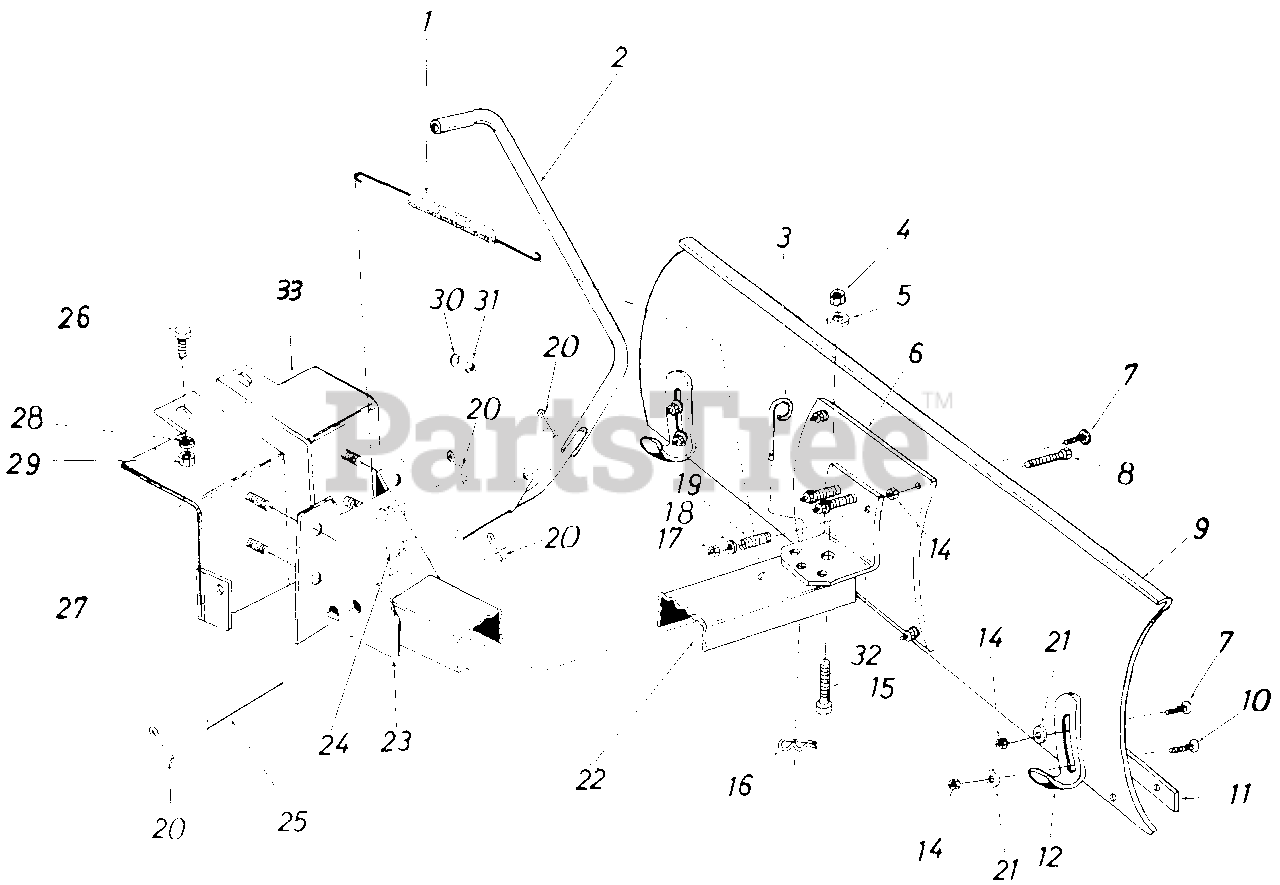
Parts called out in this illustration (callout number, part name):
1	Extension Spring
2	Lift Handle Ass'y.
3	Pivot Lock Pin
4	Hex Cent. L-Nut 1/2-13 Thd.
5	Fl-Wash. 17/32" I.D. x 1.25" Lg.
6	Reinforcement Plate
7	Carriage Bolt 5/16-18 x .75" Lg.
8	Hex Bolt 3/8-18 x 3.75" Lg. Grade 5
9	42" Blade
10	Carriage Bolt 5/16-18 x 1" Lg.
11	42" Wear Plate
12	Shoe Skid
14	Hex Cent. L-Nut 5/16-18 Thd.
15	Hex Bolt 1/2-13 x 1.25" Lg.
16	Int. Cotter Pin
17	Hex Cent, L-Nut 3/8-16 Thd.
18	Fl-Wash. 3/8" I.O.
19	Compression Spring
20	Cotter Pin 1/8" Dia. x 1" Lg.
21	Fl-Wash. 5/16" I.O.
22	Push Bar Channel
23	Pivot Support Bracket
24	Lift Link
25	Channel Pivot Shaft
26	Hex Bolt 3/8-16 x 1" Lg. Grade 5
27	Support Bracket - R.H.
28	L-Wash. 3/8" I.D.
29	Hex Nut 3/8-16 Thd.
30	L-Wash. 3/8" I.D.
31	Hex Jam Nut 3/8-16 Thd.
32	Support Bracket
33	Support Bracket-L.H.
